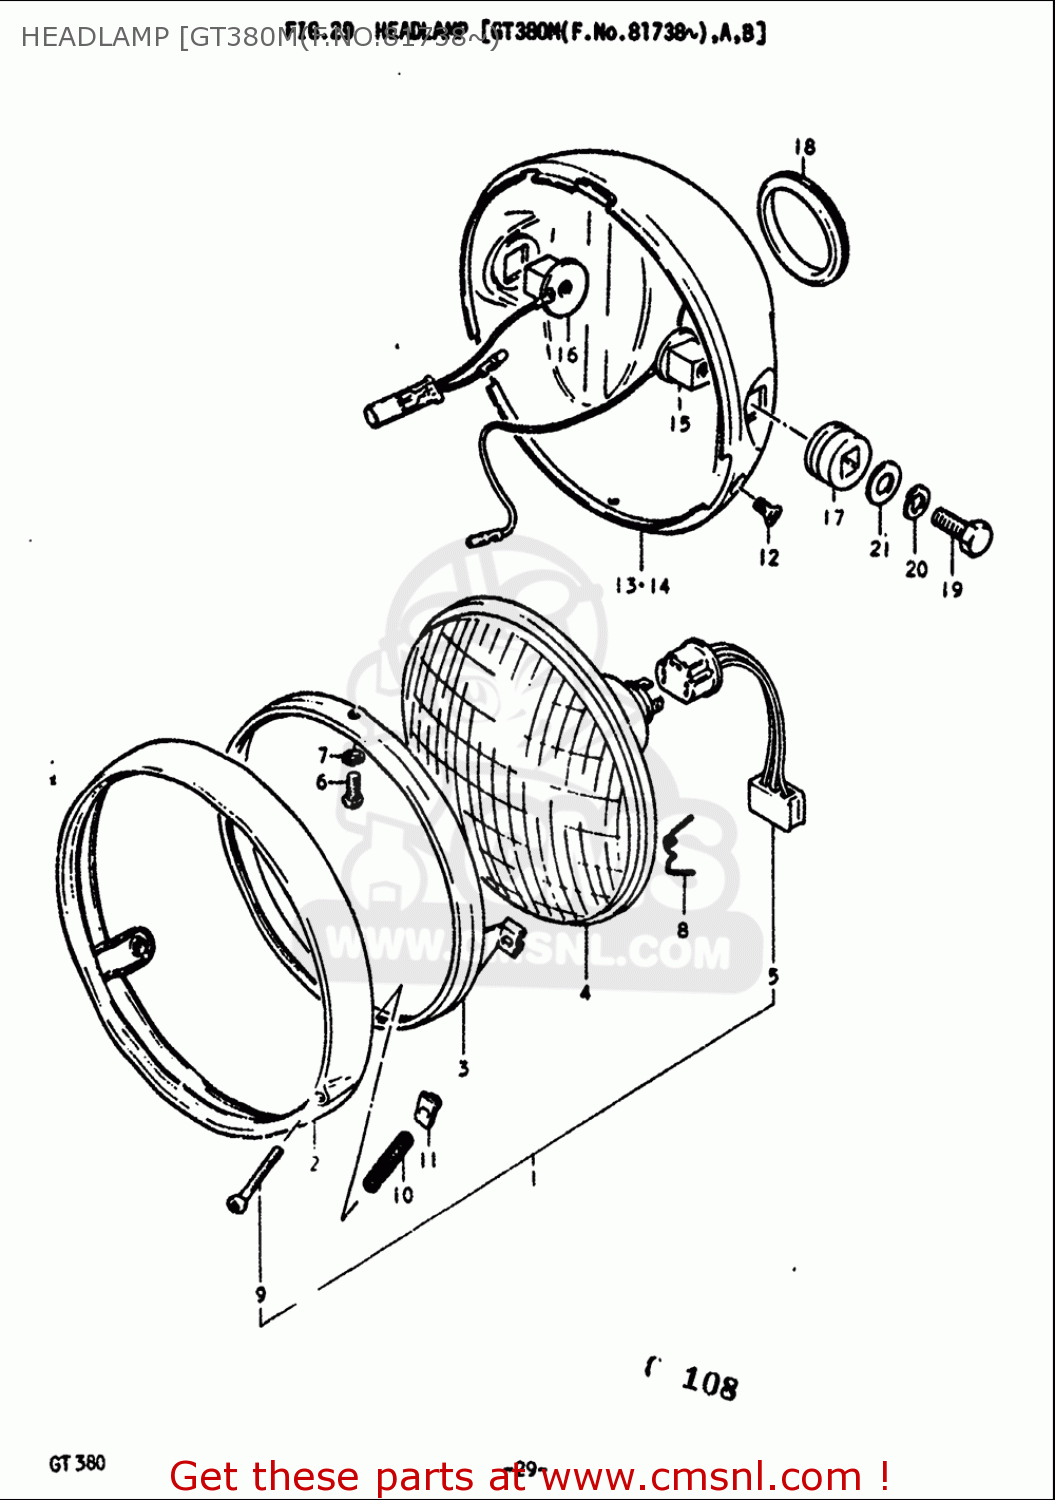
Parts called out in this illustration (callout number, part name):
5	LEAD WIRE,HEADLAMP
6	SCREW
7	WASHER,LOCK
8	SPRING
10	SPRING
11	NUT
12	SCREW
13	HOUSING,HEADLAMP
17	CUSHION,HEADLAMP HOUSING
18	GROMMET,HEADLAMP HOUSING
19	BOLT
20	WASHER,LOCK
21	WASHER
